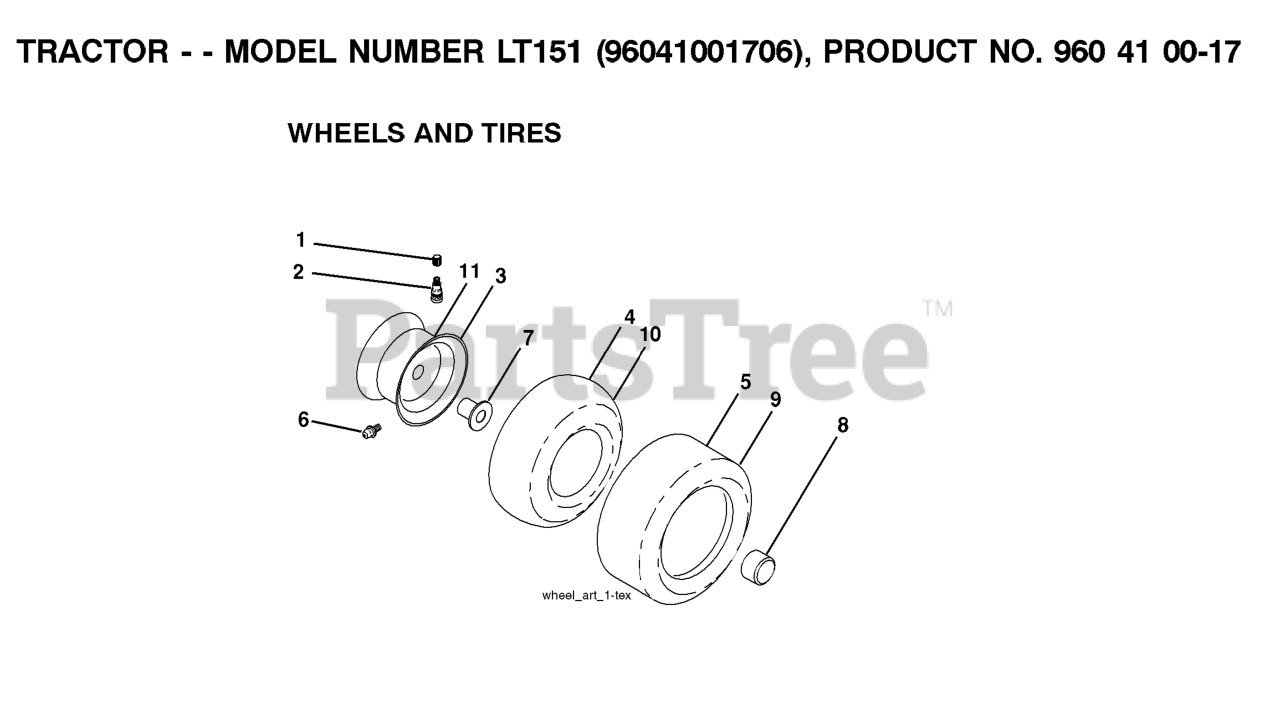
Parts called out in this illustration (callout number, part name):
2	VALVE STEM LT
3	TIRE HEAVY DUTY
4	TUBE.5.3/4.5/6
5	RIM ASM 6" FRONT SILVER
6	FITTING LT
7	BEARING T
8	CAP, AXLE BLK
9	TIRE HEAVY DUTY
10	TUBE
11	RIM ASM 8" REAR SILVER
